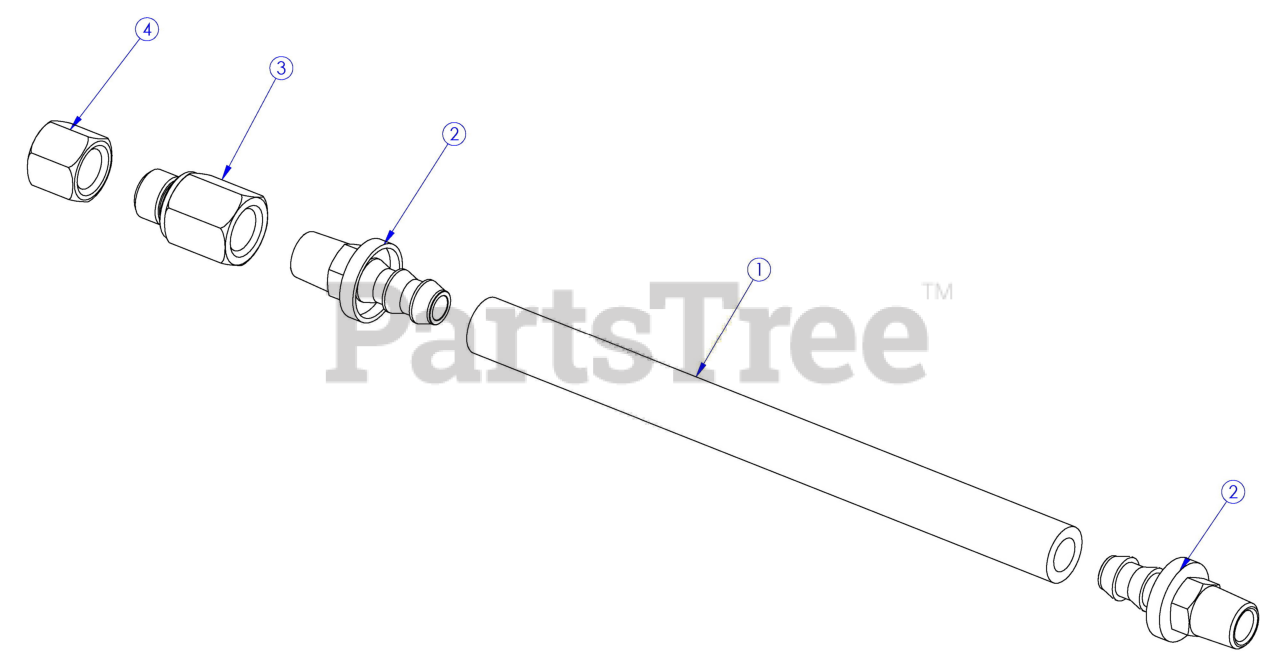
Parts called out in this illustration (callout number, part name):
1	Hose, Oil Drain
2	Fitting, Oil Drain Barb
3	Fitting, 1/4 Npt To 14Mm
4	Cap, Oil Drain
